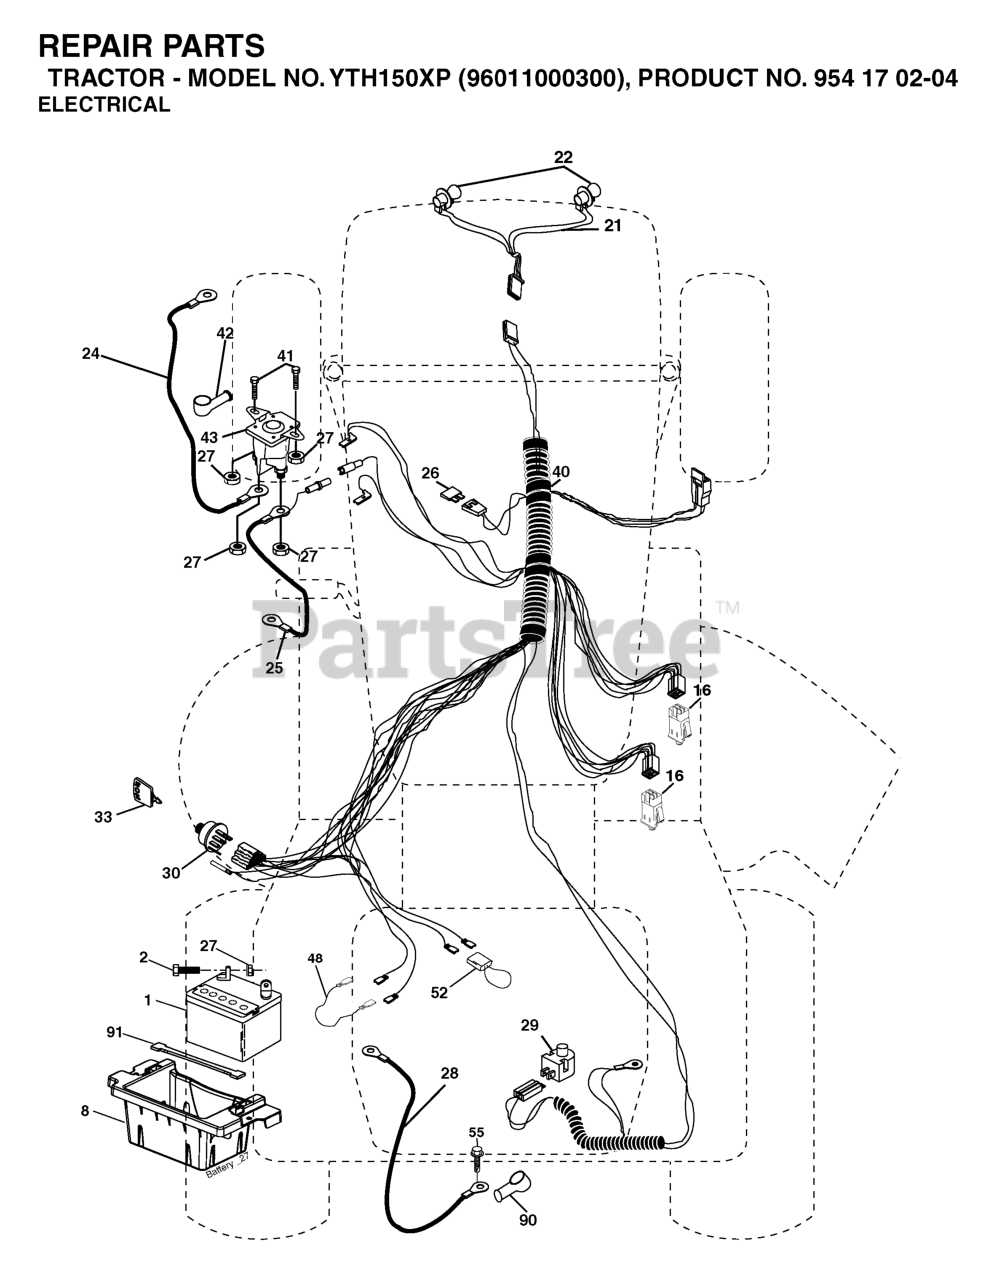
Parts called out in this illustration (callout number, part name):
1	BATTERY 12V .35 AMP
2	BOLT.HEX.1/4.X.3/4.DICHROMATE
8	BOX.BATTERY.MOUNT.FRONT.LT
16	SWITCH INTERLOOK PUSH-IN
21	HARNESS.W/LIGHT SOCKET
24	BATTERY CABLE GT
25	CABLE BATTERY 6 GA 22" W/16W
26	FUSE 20AMP
27	NUT
28	CABLE GROUND 6 GA 21" 90T BLK
29	RP.SWITCH.PLUNGER.NC.GRAY
30	IGNITION SWITCH
33	KEY MLD GEN DELTA
40	HARNESS.IGNITION
41	BOLT
42	TERMINAL COVER
43	SOLENOID
48	ADAPTER.AMMETER
52	WIRE PROTECTION LOOP
55	Screw 5/16-18 x 1/2 Hex, Self Tapping 5/16-18 x 1/2
90	COVER TERMINAL
91	STRAP.BATTERY.MOUNT.FRONT(2 2)
